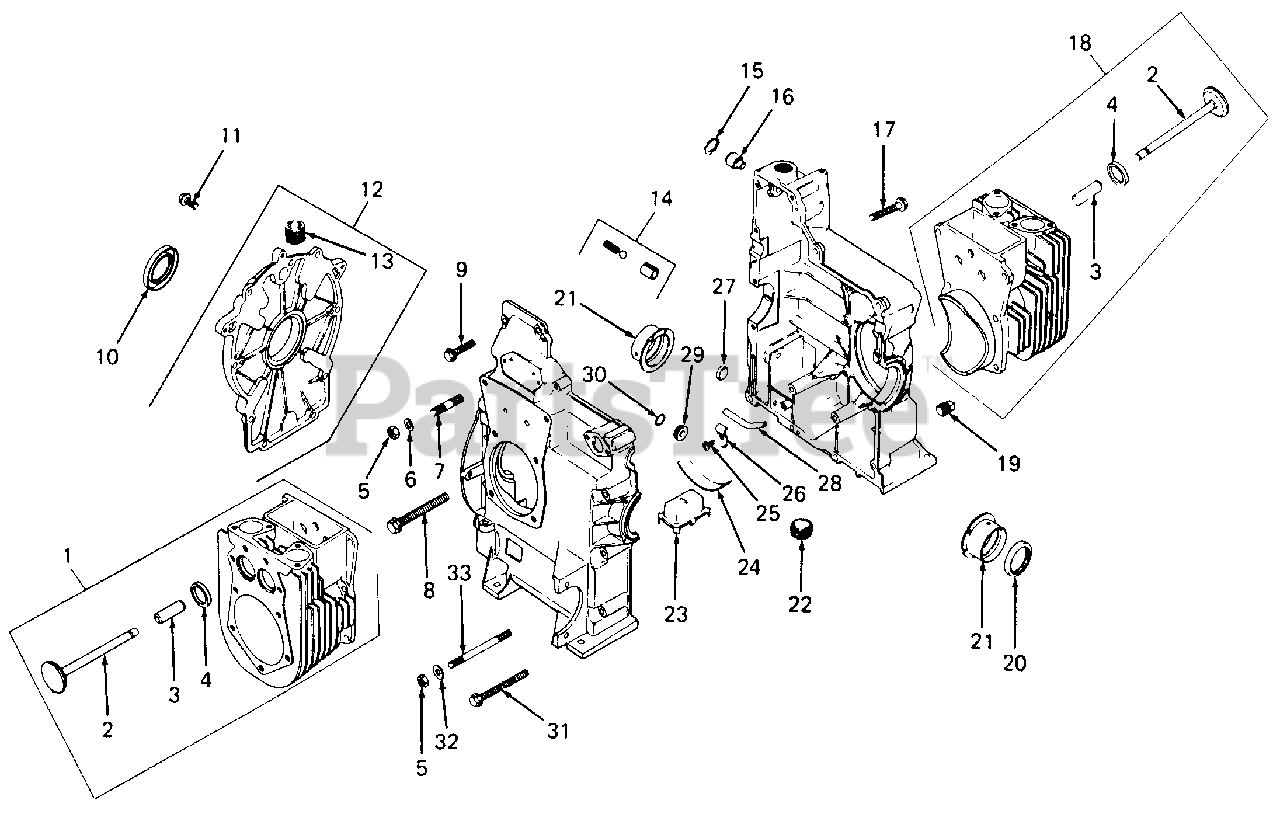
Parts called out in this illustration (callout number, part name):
1	Kit, #2 Cylinder Barrel
2	Valve, Exhaust
3	Guide, Valve
4	Insert, Valve Seat
5	Nut, Hex, 5/16-18
6	Washer, Flat, 5/16
7	Stud, Step, 5/16-18 X .75, 3/8-16 X .62, 2.0 Lg
8	Screw, Hex Flange, 3/8-16 X 3.62 Lg
9	Screw, Hex Flange, 5/16-18 X 1.5 Lg
10	Seal, Rear Oil
11	Screw, Hex Wash Hd, 5/16-18 X 1.0 Lg
12	Kit, Closure Plate
13	Plug, Hex Ctsk, 1/8 NPTF
14	Kit, Oil Relief
15	Ring, Retaining
16	Shaft, Governor
17	Screw, Hex Flange, 5/16-18 X 2.0 Lg
18	Kit, #1 Cylinder Barrel
19	Plug, Hex Ctsk, 3/8 NPTF
20	Seal, Front Oil
21	Bearing, Sleeve (Std)
22	Plug, Bottom Drain, 3/8
23	Housing, Oil Pickup
24	Clamp, Spring
25	Screw, Hex Wash Hd, #10-32 X .43 Lg
27	Plug, Cup
28	Tube, Oil Pickup
29	Plug, 3/4 OD
31	Screw, Hex Flange, 5/16-18 X 3.5 Lg
32	Washer, Plain
33	Stud, 5/16-18 X 4.12 Lg
